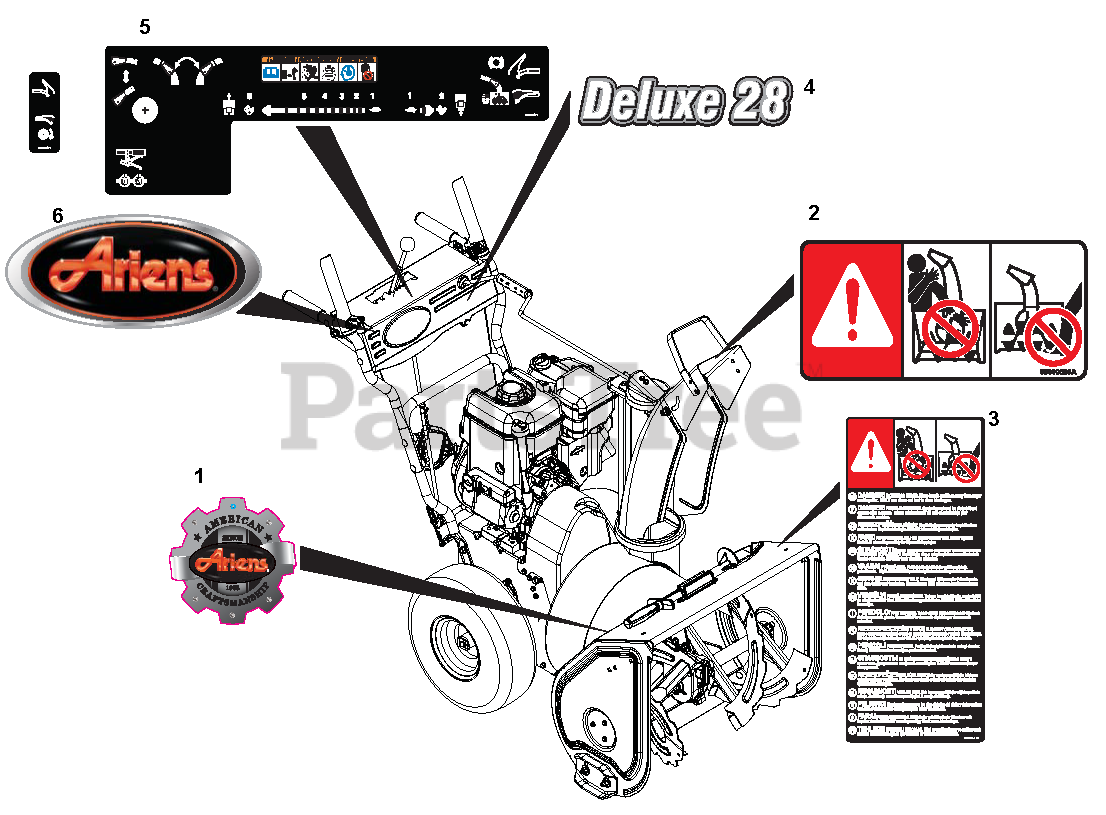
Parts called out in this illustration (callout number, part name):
1	Decal, Ariens Heritage
2	DECAL, DANGER
3	DECAL, DANGER - ROTATING PARTS
4	DECAL, DELUXE 28 SM DASH
5	DECAL,CONTROL,REMOTE CAP/CLICK
6	DECAL, ARIENS JEWEL
